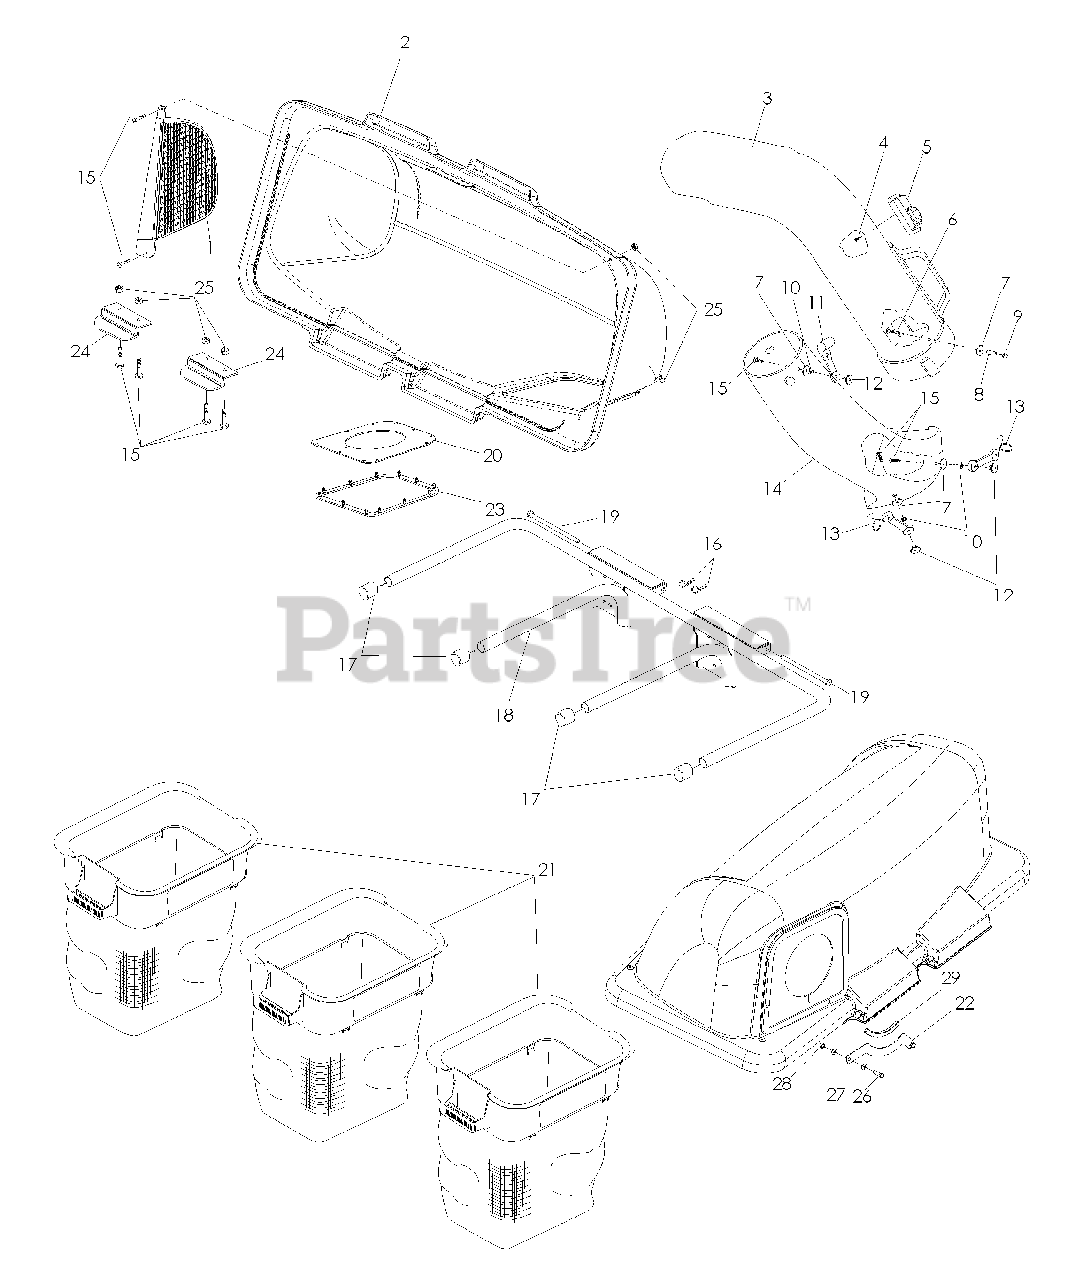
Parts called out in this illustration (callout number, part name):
1	SCREEN, COVER
3	CHUTE, UPPER
4	SCREW #10-14 x 1/2 SPEC
5	DUMP BAG INDICATOR
6	SCREW #10-24 x 1 1/8
7	WASHER 3/16 x 3/4 x 16 GA
8	SPACER, SPLIT
9	NUT #10-24 ACORN
10	LOCKWASHER 3/16
11	LATCH, CHUTE
12	NUT, WELD
13	LATCH, ASSEMBLY
14	CHUTE, LOWER 46" DECK
15	SCREW #10-24 x 5/8
17	PLUG, TUBING END
18	BAGGER, FRAME
19	PIN, HINGE
20	SEAL, COVER
21	CONTAINER, SOFT BAG
22	SUPPORT, CHUTE
23	GASKET, COVER
24	HANDLE, BAGGER COVER
25	NUT #10-24 CROWNLOCK
26	HCS 5/16-18 x 1 1/4
27	WASHER 5/16 SAE FLT
28	NUT 5/16-18 HEx NYLOC
29	FLEx TRIM
